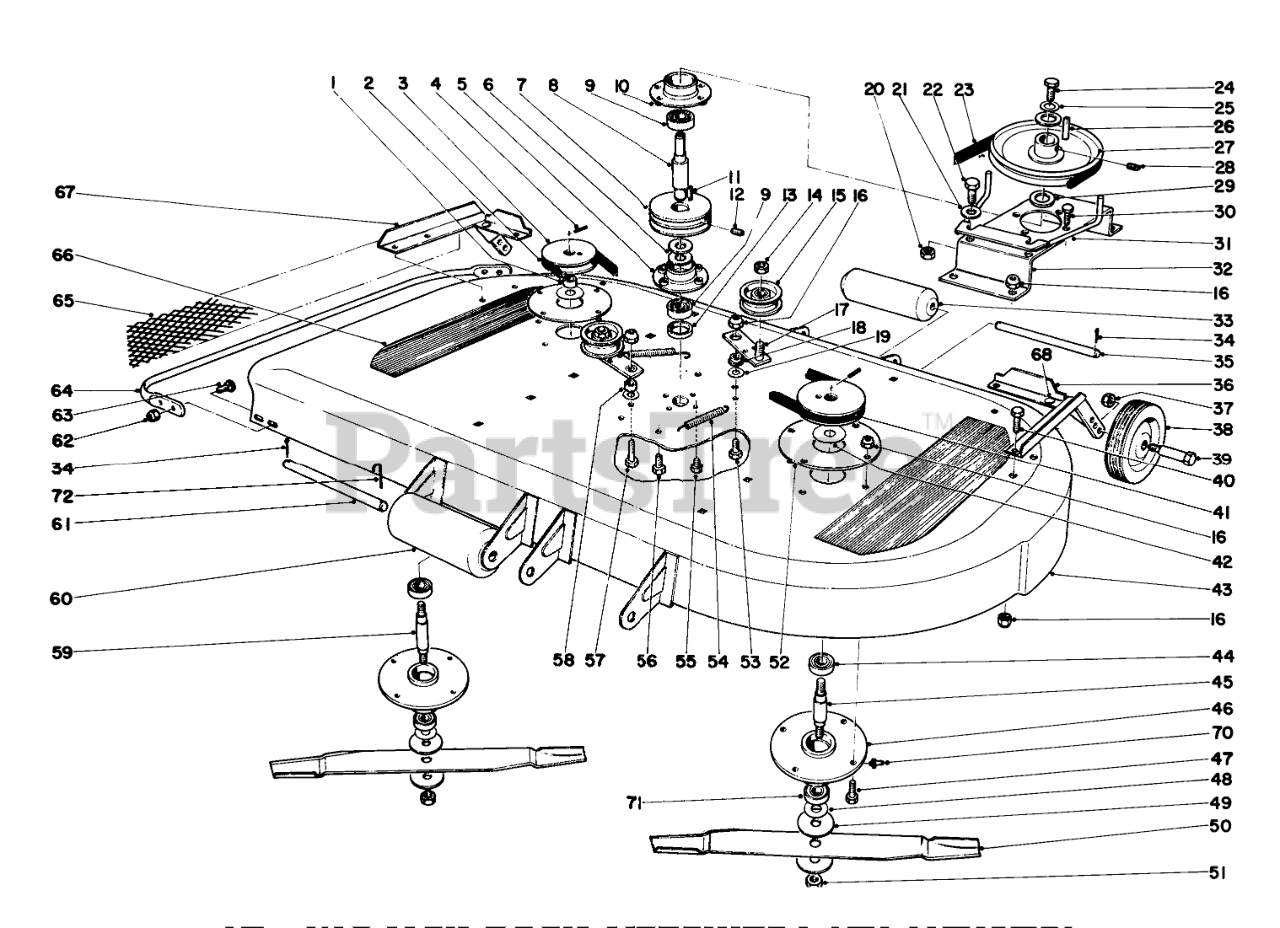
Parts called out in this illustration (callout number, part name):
1	Spacer
2	Belt
3	Pulley
4	Roll Pin
5	Bearing Housing
6	Washer
7	Pulley
8	BLADE DRIVE SHAFT
9	Bearing
10	Bearing Housing
11	KEY-WOODRUFF
12	Set Screw
13	Spacer
14	NUT-JAM
15	Pulley
16	Nut
17	Idler Arm
18	Bushing
19	WASHER-FLAT
20	Nut
21	WASHER-FLAT
22	SCREW-HH
23	V-BELT
24	SCREW-HH
25	Washer
26	KEY-SQUARE
27	Pulley
28	Set Screw
29	Washer
30	Sems Screw
31	Belt Guide
32	Support
33	Roller
34	PIN-COTTER
35	ROLLER SHAFT
36	Bracket
38	Wheel
40	SCREW-HH
42	Washer
43	Housing
44	Bearing
45	LH BLADE SHAFT
46	MOWER SPINDLE HOUSING
47	SCREW-HH
48	WASHER
49	WASHER
50	Blade
52	Washer
53	SCREW-HH
54	IDLER ARM SPRING
55	Sems Screw
56	SCREW-HH
57	SCREW-HH
58	Spacer
59	Blade Shaft
60	Roller
61	ROLLER SHAFT
63	SCREW-CARR
64	Guard
65	Mulcher
66	Foot Pad
67	Bracket
68	Plug Button
70	FITTING-GREASE
71	.6693 RP BALL BEARING
72	Retainer Roller
